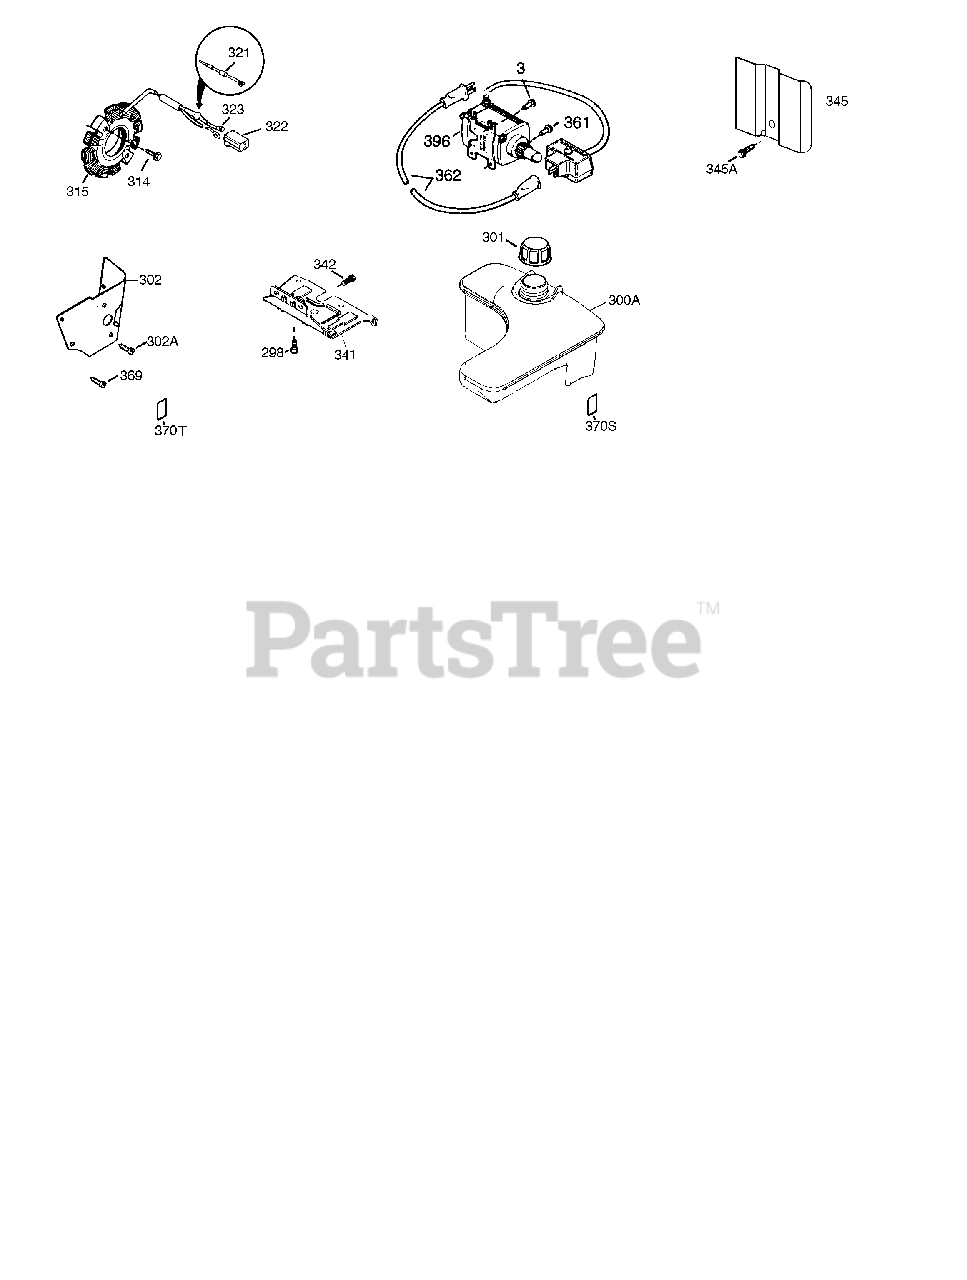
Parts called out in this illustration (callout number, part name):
3	Screw, 1/4-20 x 1/2" (Upper Mounting Screws for 120-Volt Electric Starter Motor)
128	Belleville Washer
163	Lock Washer
178	Nut & Lock Washer 1/4-28
293A	Screw, T-30, 1/4-20 x 27/32"
298	Screw, 1/4-15 x 3/4"
301	Fuel Cap (Red Plastic)(1-1/2" I.D.)
302	Fuel Tank Extension used with Premium Tank
309	Screw, 10-32 x 5/16"
314	Screw, 1/4-20 x 3/4"
323	Terminal
329A	Screw, 10-32 x 23/64"
341	Fuel Tank Bracket
342A	Screw, 5/16-18 x 7/8"
345	Heat Baffle
370	Decal - Primer - International Symbol
370	-1
370	Decal - Tecumseh Logo for Top of Reco il Starter
370	Warning Decal (Bilingual)
370	Decal - Speed Control, Choke, & Key
396	Electric Starter Motor (120 Volt)
704	Screw, 1/4-20 x 5/8"
710	Compression Spring
711	Screw, T-10, 6-32 x 41/64"
